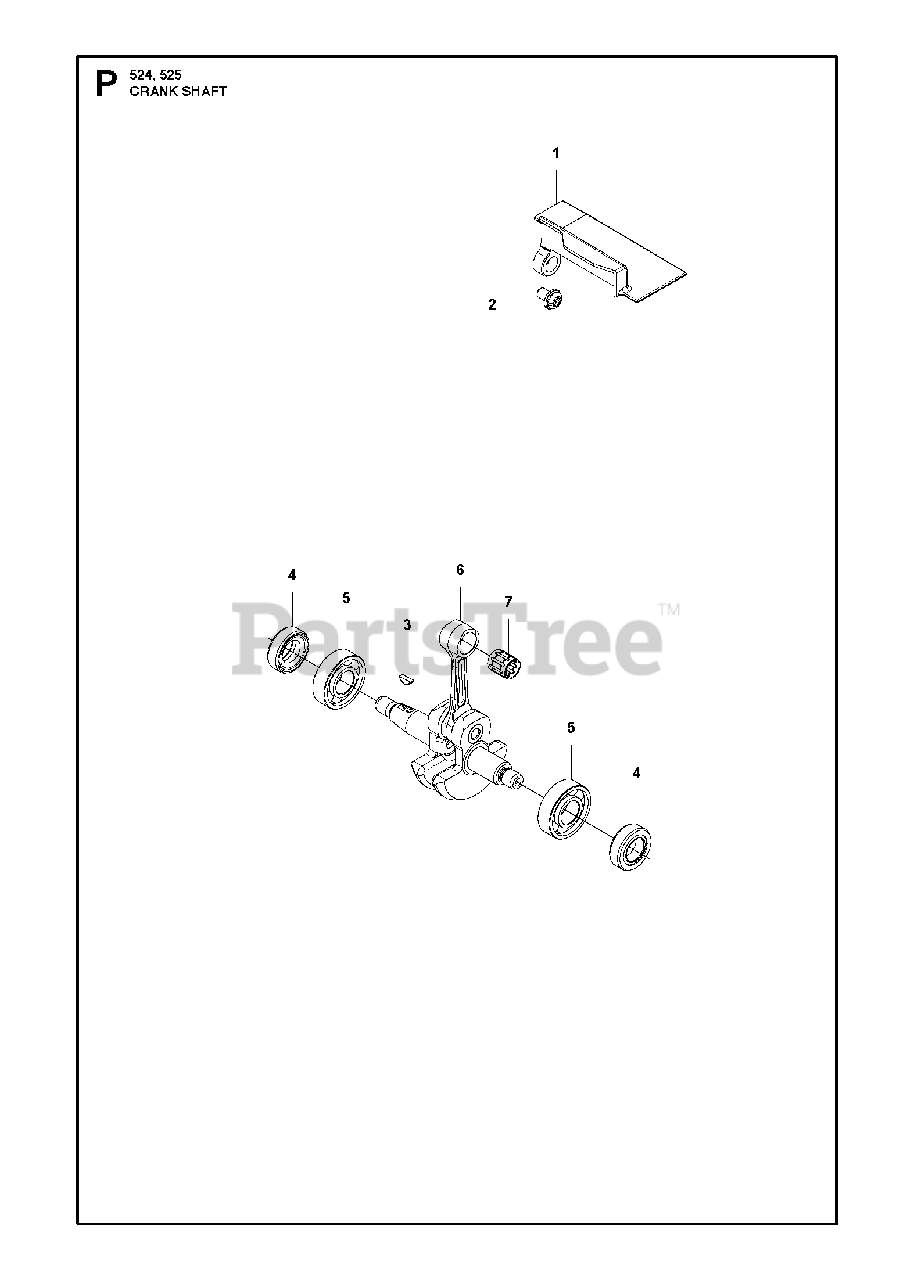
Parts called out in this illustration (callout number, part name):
1	MUFFLER PLATE
5	BEARING
6	CRANKSHAFT COMPLETE
